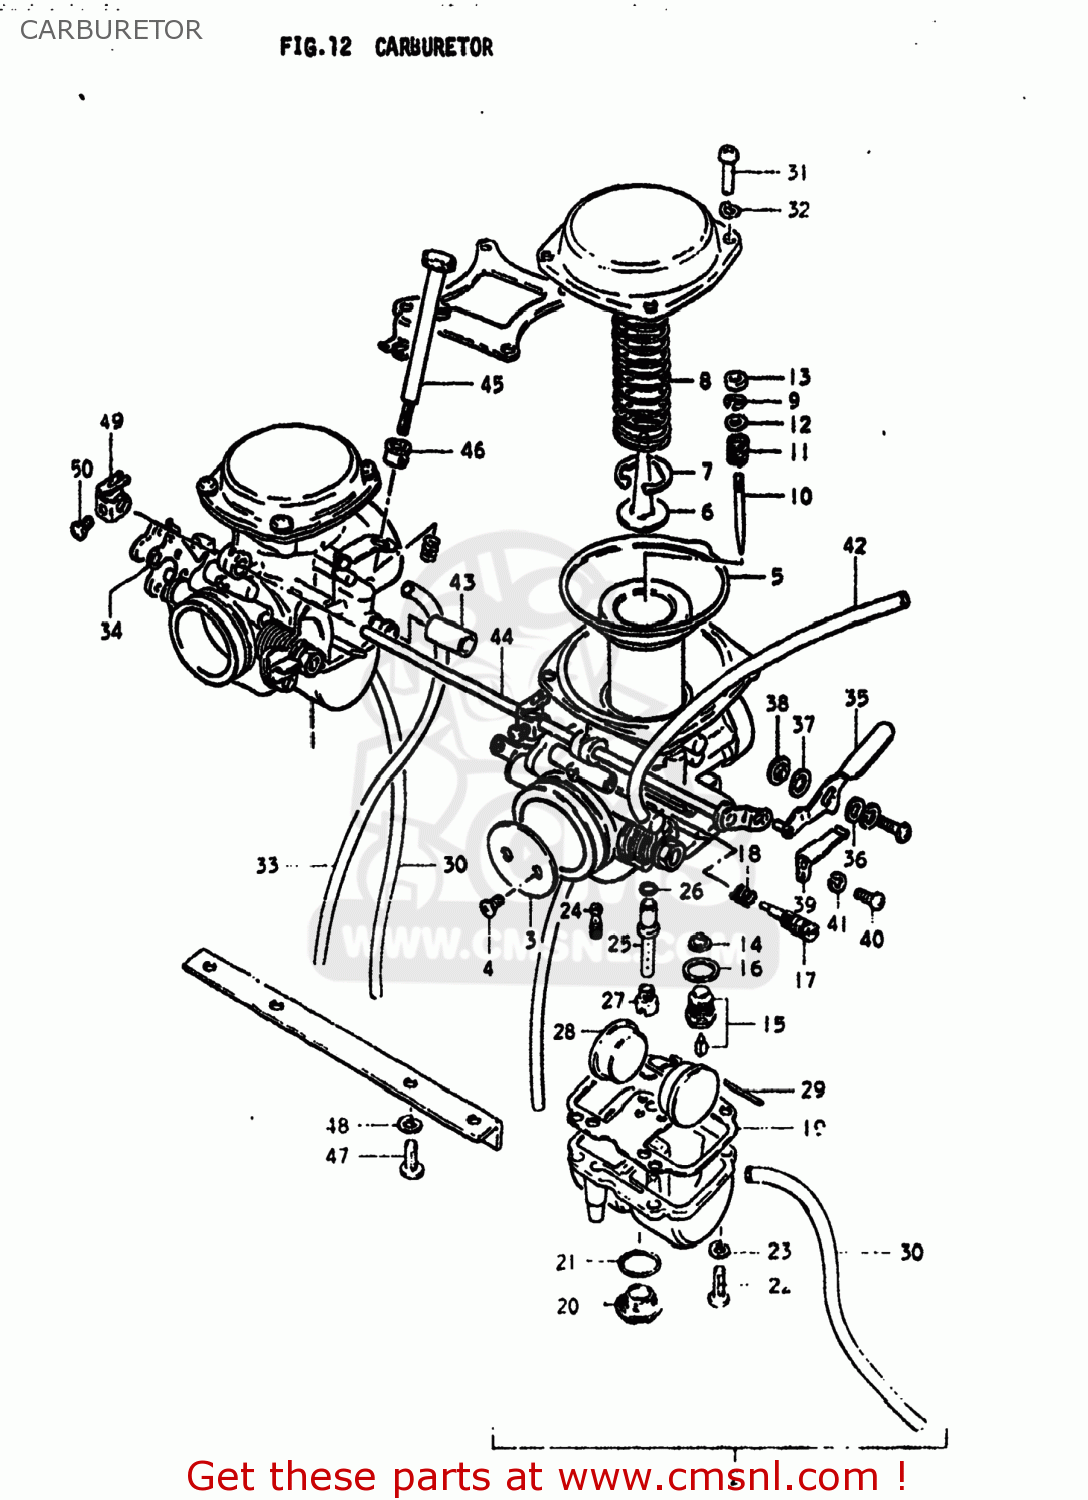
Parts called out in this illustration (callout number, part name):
1	CARBURETOR ASSEMBLY
2	CARBURETOR ASSEMBLY
3	VALVE,THROTTLE
4	SCREW
5	DIAPHRAGM ASSEMBLY
6	HOLDER,GUIDE
7	E RING
8	SPRING,DIAPHRAGM
9	CLIP
10	NEEDLE JET
11	SPRING
12	WASHER
13	RING
14	FILTER
15	VALVE ASSY,NEEDLE
16	GASKET,MAIN JET HOLDER (NAS)
17	SCREW,PILOT AIR
18	SPRING,THROTTLE SCREW
19	GASKET,FLOAT CHAMBER (NAS)
20	SCREW,GUIDE
21	O-RING
22	SCREW
23	LOCK WASHER
24	JET,PILOT
25	JET,NEEDLE
26	O-RING
27	SET, MAIN
28	FLOAT
29	PIN,FLOAT
30	HOSE
31	SCREW
32	LOCK WASHER
33	HOSE
34	GASKET
35	LEVER
36	WASHER,STARTER LEVER
37	WASHER,STARTER LEVER
38	RING,STARTER LEVER
39	SPRING
40	SCREW
41	LOCK WASHER
42	HOSE
43	HOSE
44	SHAFT,STARTER
45	ADJUSTER
46	BUSH
47	SCREW 6X12
48	LOCK WASHER
49	LEVER, STARTER
50	SCREW
